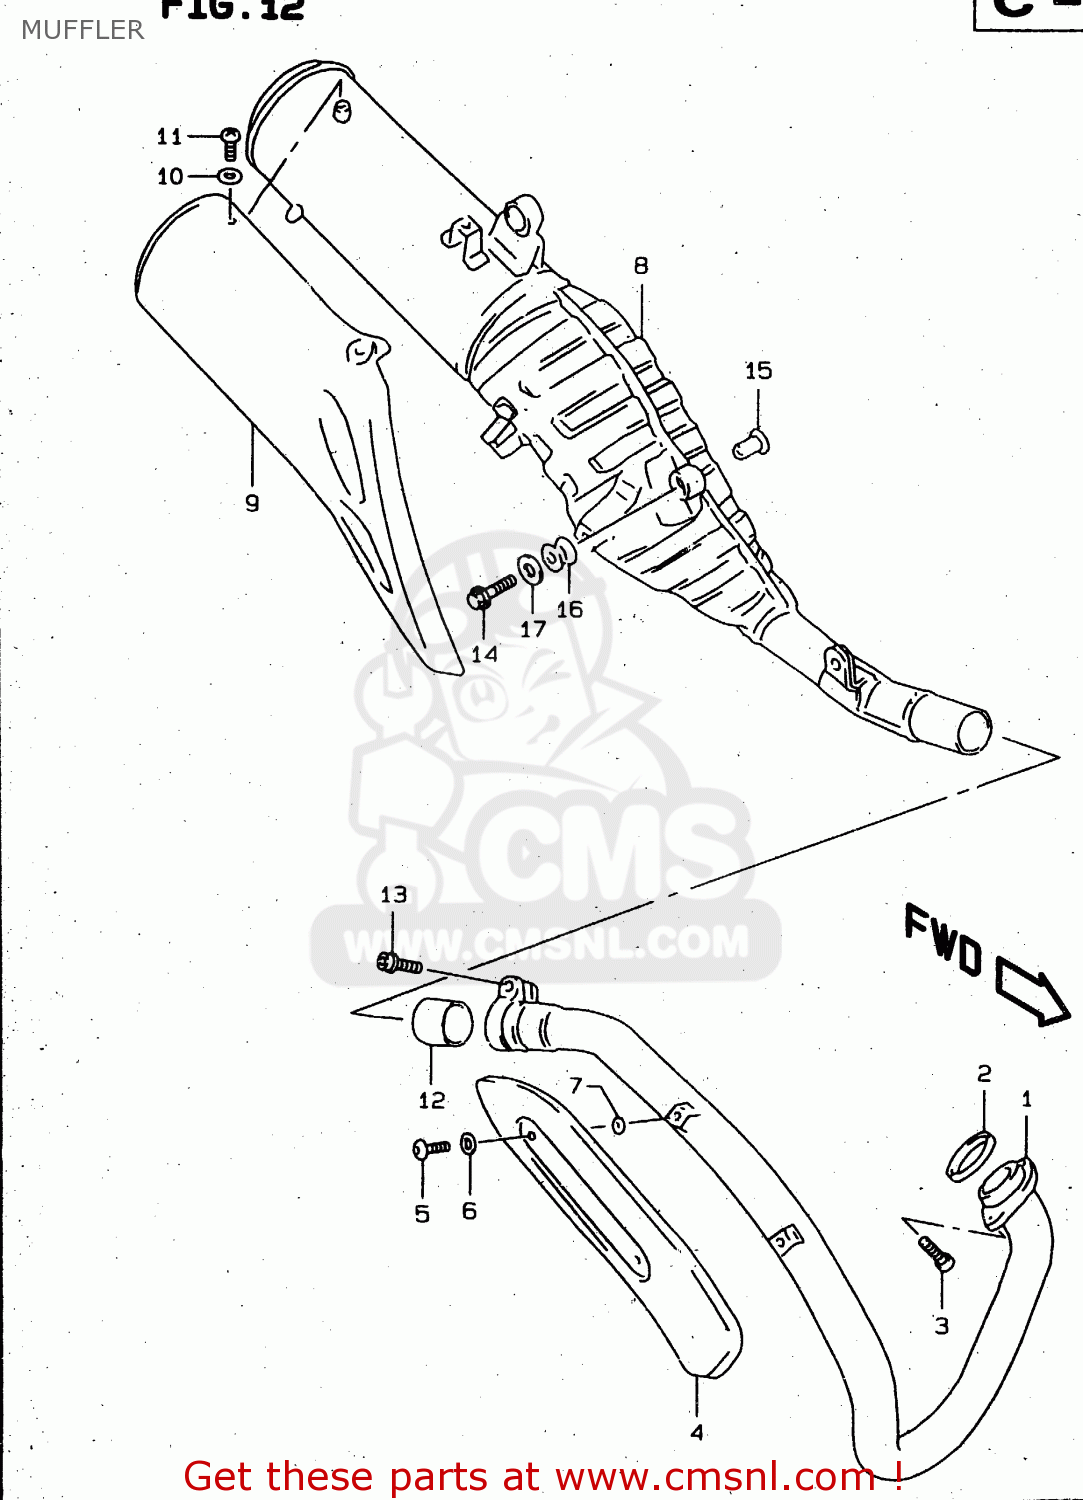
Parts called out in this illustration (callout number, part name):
1	PIPE,EXHAUST
2	GASKET,EXHAUST PIPE (NAS)
3	BOLT
4	COVER,EXHAUST PIPE
5	SCREW(6X10)
6	WASHER(6.5X13X1.0)
7	GASKET(6X16X1.4) (NAS)
8	BODY, MUFFLER
9	COVER ASSY,MUFFLER
10	WASHER(6.5X13X1.0)
11	SCREW(6X10)
12	CONNECTOR,MUFFLER
13	BOLT
14	BOLT(8X30)
15	SPACER(8.6X12X17.5)
16	CUSHION
17	WASHER(8.5X28X1.6)
